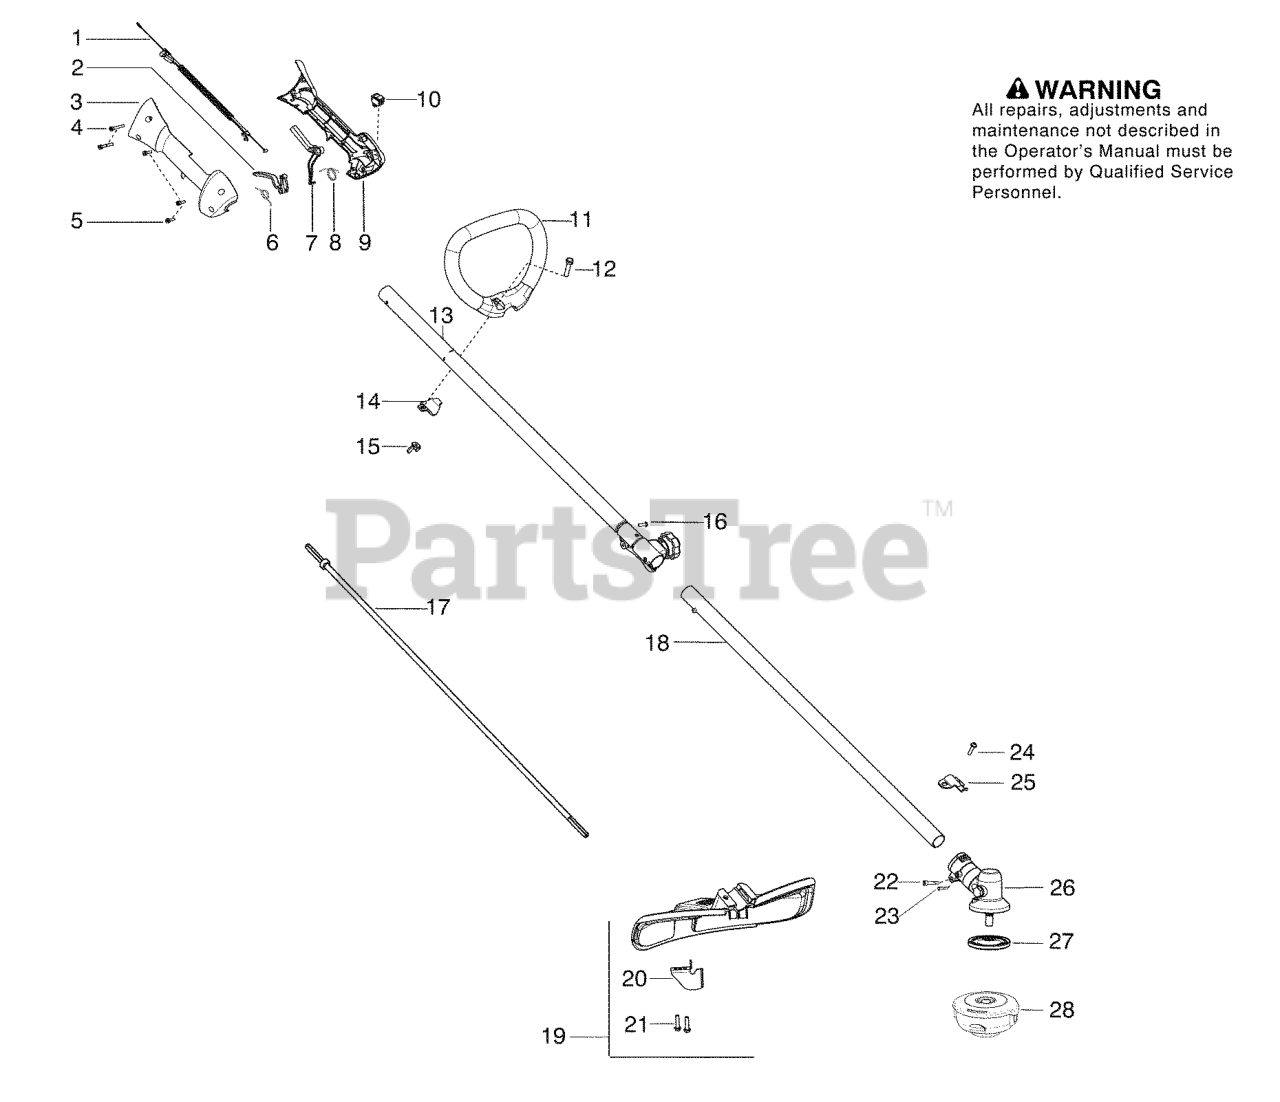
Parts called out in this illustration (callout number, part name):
1	ASSY-CABLE WIRE HARNESS
2	TRIGGER THROTTLE
3	HOUSING-THROTTLE RH
5	SCREW M4 X 1.75 PT 16MM
6	SPRING TRIGGER
7	THROTTLE LOCKOUT
8	SPRING LOCKOUT
9	HSG THROTTLE LH
10	KIT SWITCH
12	BOLT, TYPE 2
13	KIT DRIVESHAFT UPPER SHAFT
14	CLAMP ASSIST HANDLE
15	WINGNUT, TYPE 2
18	KIT LOWER SHAFT
19	KIT COBI SHIELD
20	Limiter - Line
22	SCREW - CARB. ADAPTOR
24	SCREW 1/4-20 X 7/8 (TAP
25	BRACKET SHIELD STRAIGHT SHAFT
26	ASSY GEARBOX
27	DRIVE DISC
28	T25 TRIM HEAD 10MM LH
